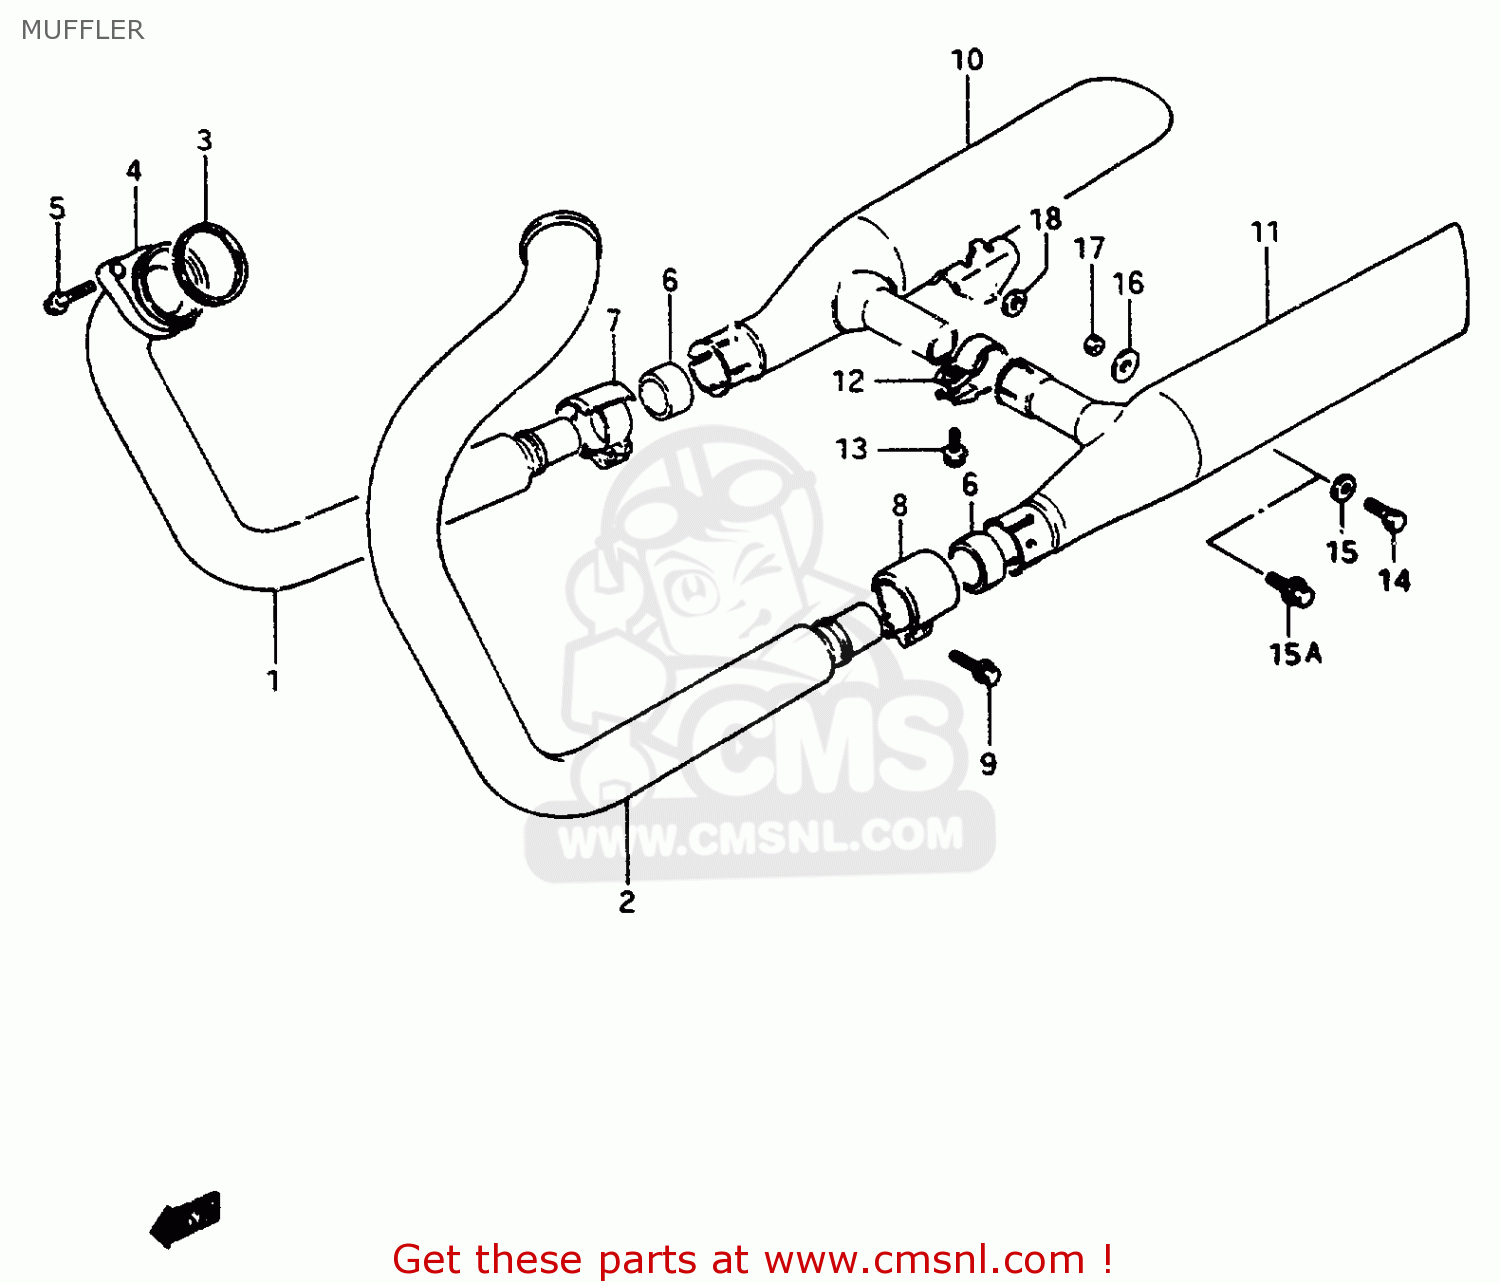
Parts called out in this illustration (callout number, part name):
1	PIPE,EXHAUST,R
2	PIPE,EXHAUST,L
3	GASKET,EXHAUST PIPE (NAS)
4	CLAMP,EXHAUST PIPE
5	BOLT(8X35)
6	CONNECTOR,EXHAUST PIPE
7	CLAMP,MUFFLER CONNECTOR,R
8	CLAMP,MUFFLER CONNECTOR,L
9	BOLT
10	BODY,MUFFLER,R
11	BODY,MUFFLER,L
12	CLAMP,EXHAUST COUPLER
13	BOLT
14	BOLT
15	WASHER
15A	BOLT
16	WASHER
17	NUT
18	WASHER (8.5X18X3.2)
